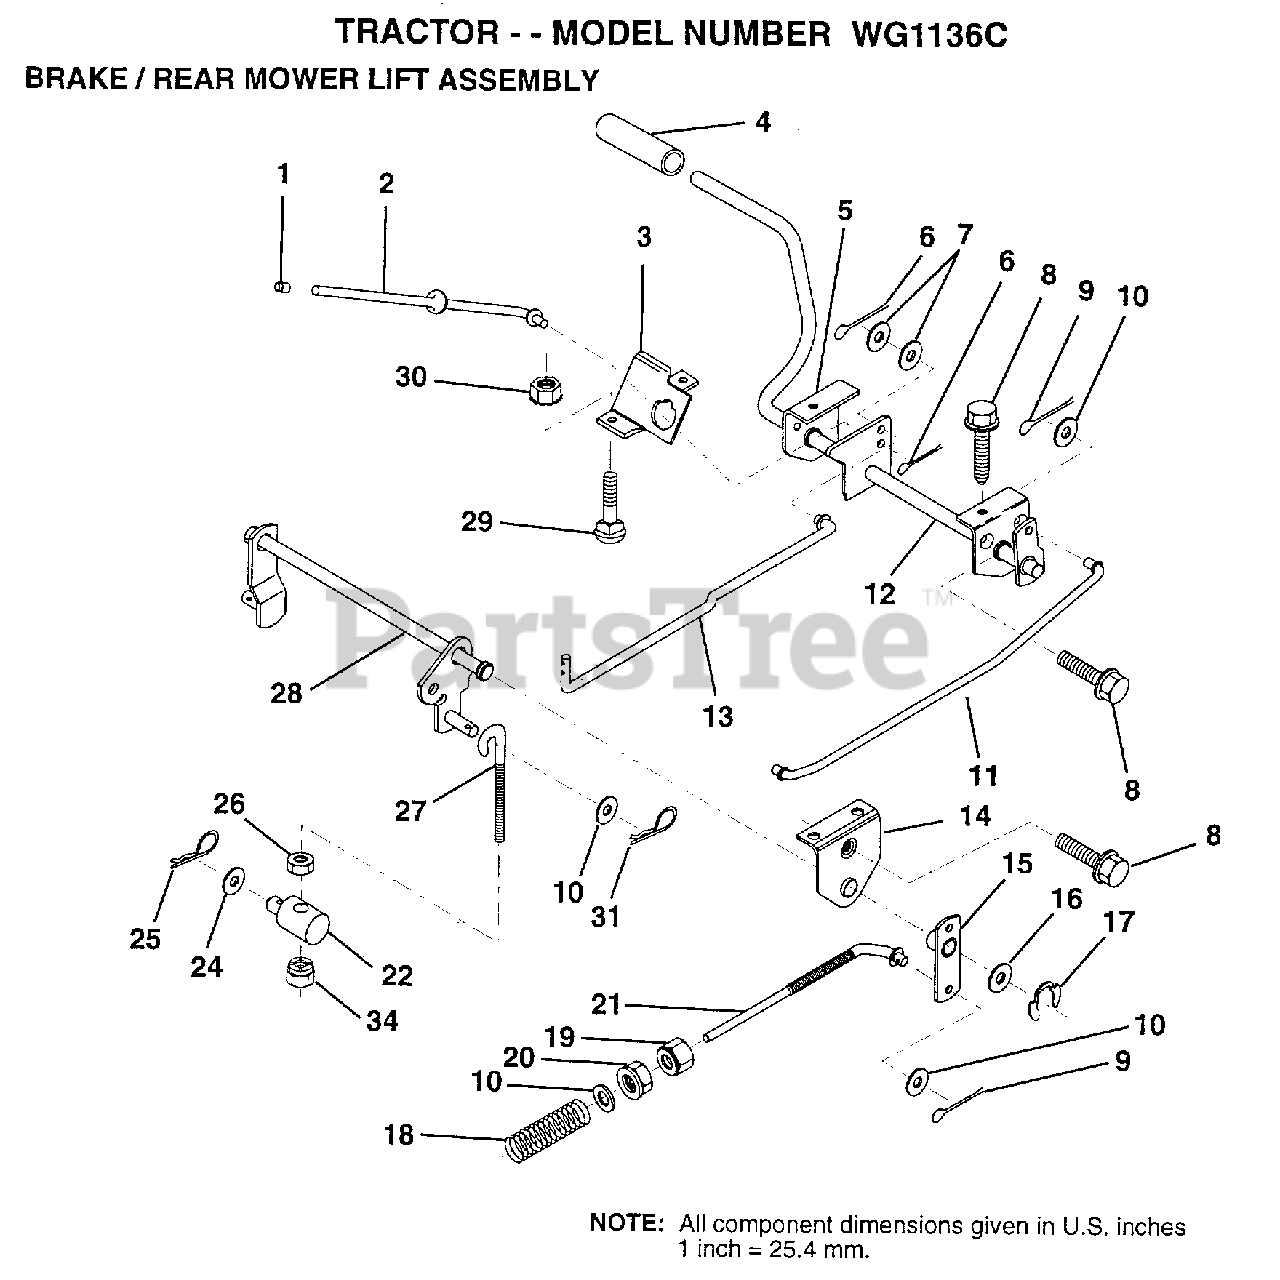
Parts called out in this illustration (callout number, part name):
1	PLUNGER CAP T
2	"ROD,PARK BRAKE"
3	"BRKT,PARK BRAKE"
4	FOOT PEDAL COVER
5	"BRKT,CLU PEDAL LH"
7	WASHER
8	SCREW LT
9	COTTER PIN
10	WASHER
11	"ROD,FRT BRAKE"
12	PEDAL ASM CL/BK36
13	"ROD,CLUTCH"
14	"BRKT,LIFT SHAFT"
15	PVT BRAKE ARM ASM
16	WASHER T
17	KLIP RING
18	SPRING ROD BRAKE
19	NUT
20	NUT
22	TRUNNION.LIFT.
24	WASHER
25	SPRING.RETAINER
26	LOCKNUT
27	"LINK, MOWER REAR"
28	LIFT ASM MOW REAR
31	RETAINER.SPRING
